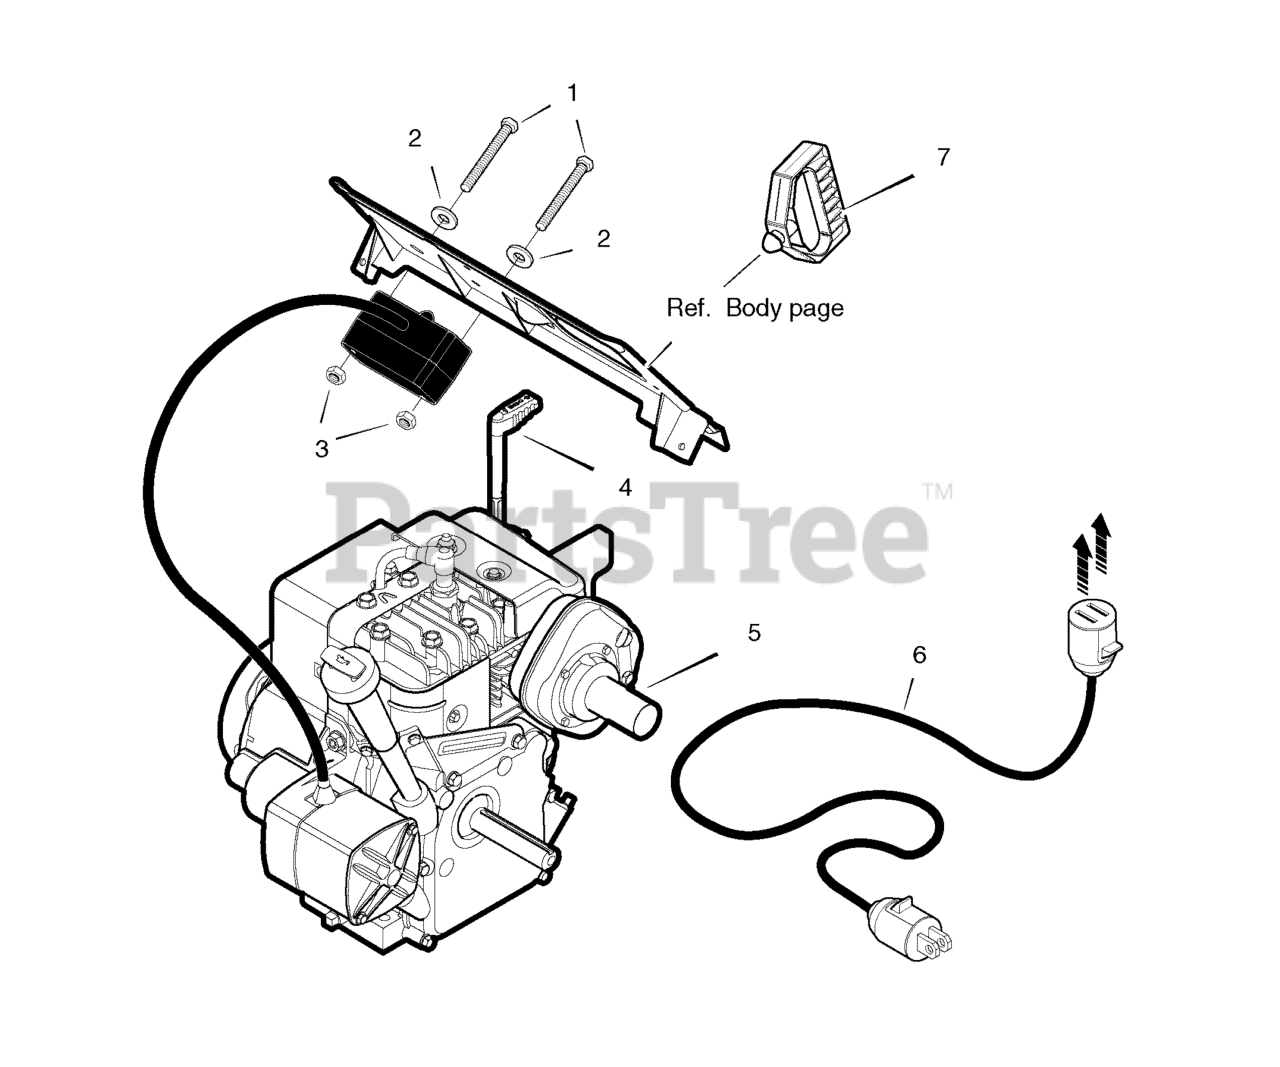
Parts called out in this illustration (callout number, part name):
1	SCREW, # 8 - 32 x 3
3	NUT, Keps
4	LEVER, Choke *
5-1	Muffler *
5-2	GASKET, Muffler *
5-3	Bolt, Muffler *
5-4	WASHER, Split Lock
5-5	NUT, Hex, 5/16 - 18
5-6	BOLT, Hex, 5/16 - 18
6	CORD, Extension
7	GRIP, Mitten
